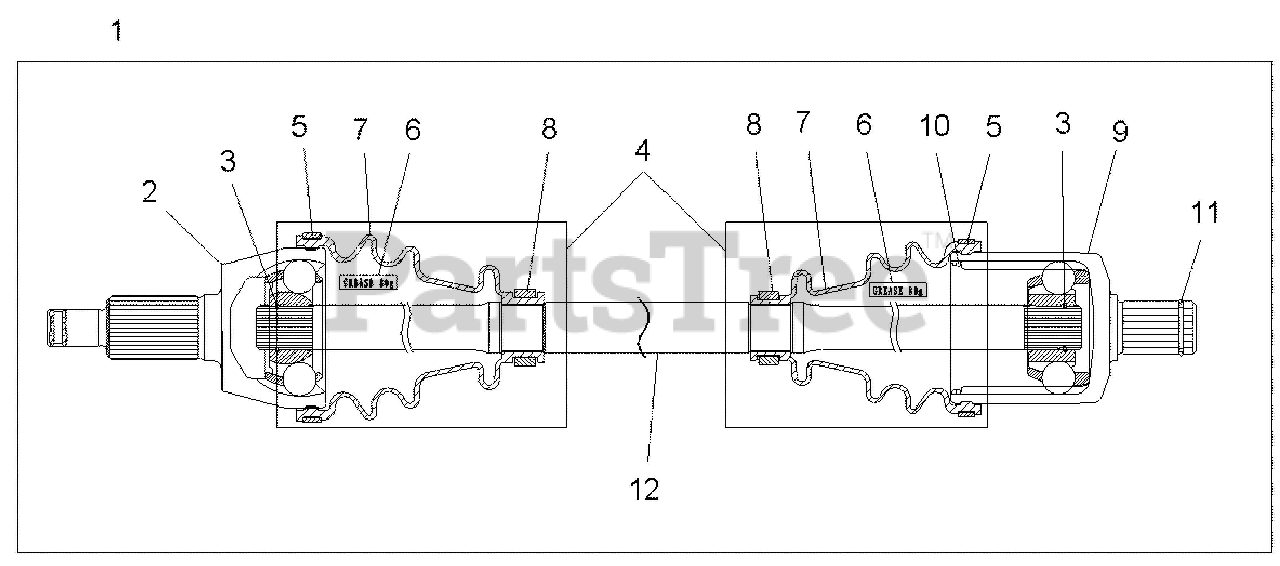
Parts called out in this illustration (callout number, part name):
1	ASM-HALF SHAFT,FRONT,LT
2	JOINT-CV,OUTER
3	CIRCLIP-1.8X22.2(PR-3011)
4	KIT-BOOT,PLUNGING JNT(PR-8062)
5	CLAMP-LARGE(PR-2019)
6	GREASE(K575/VW738)
7	BOOT(PR-0015)
8	CLAMP-SMALL(PR-0016)
9	JOINT-CV,INNER
10	CIRCLIP-2.0X61.7(PR-2016)
11	CIRCLIP-1.6X24.4(PR-2025)
12	SHAFT,23.5(PR-315)
